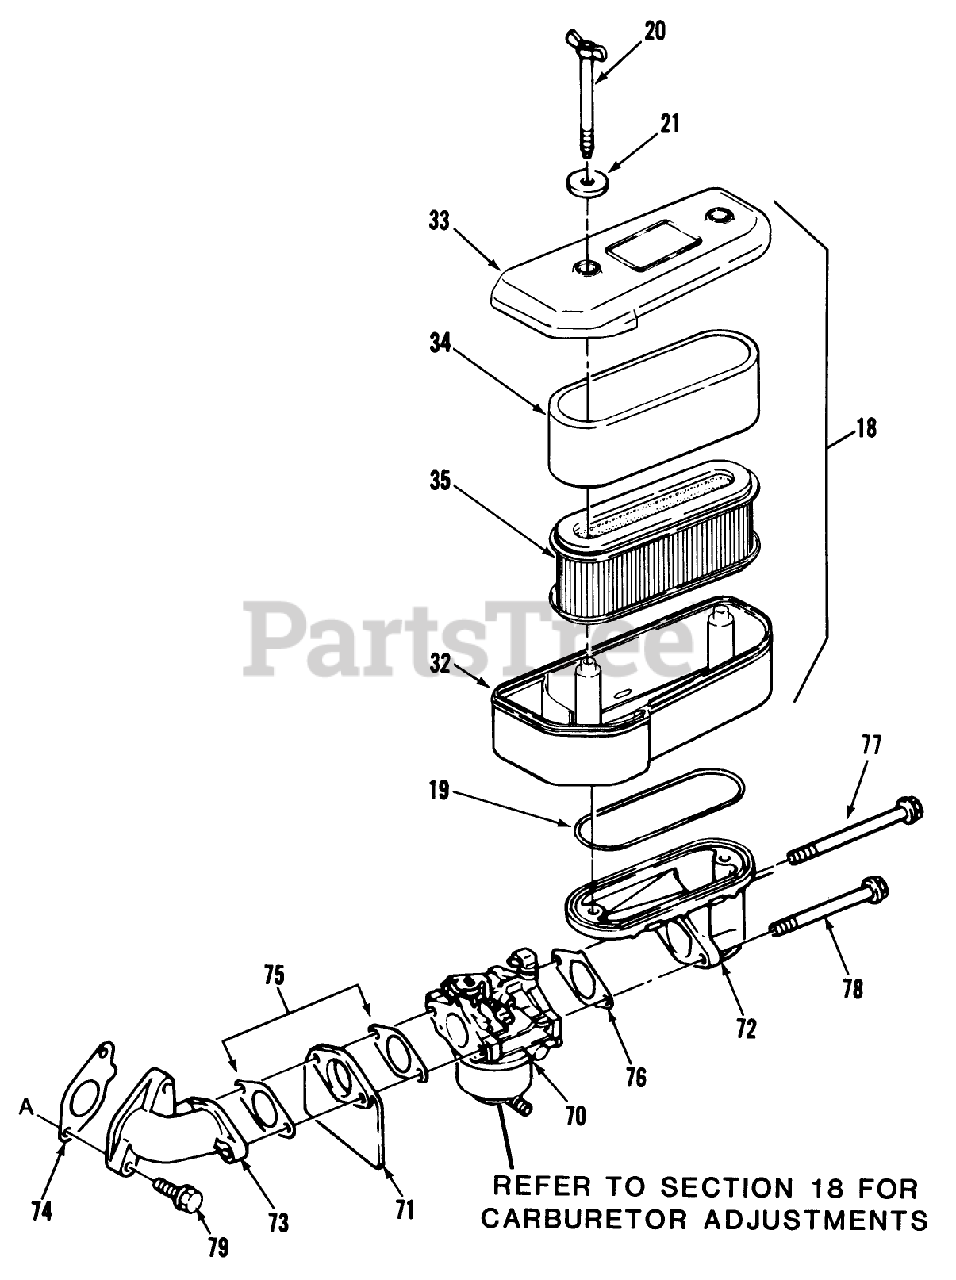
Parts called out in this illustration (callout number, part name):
18	AIR FILTER ASSY
34	ELEMENT-AIR CLEANER
73	MANIFOLD INTAKE
74	GASKET
